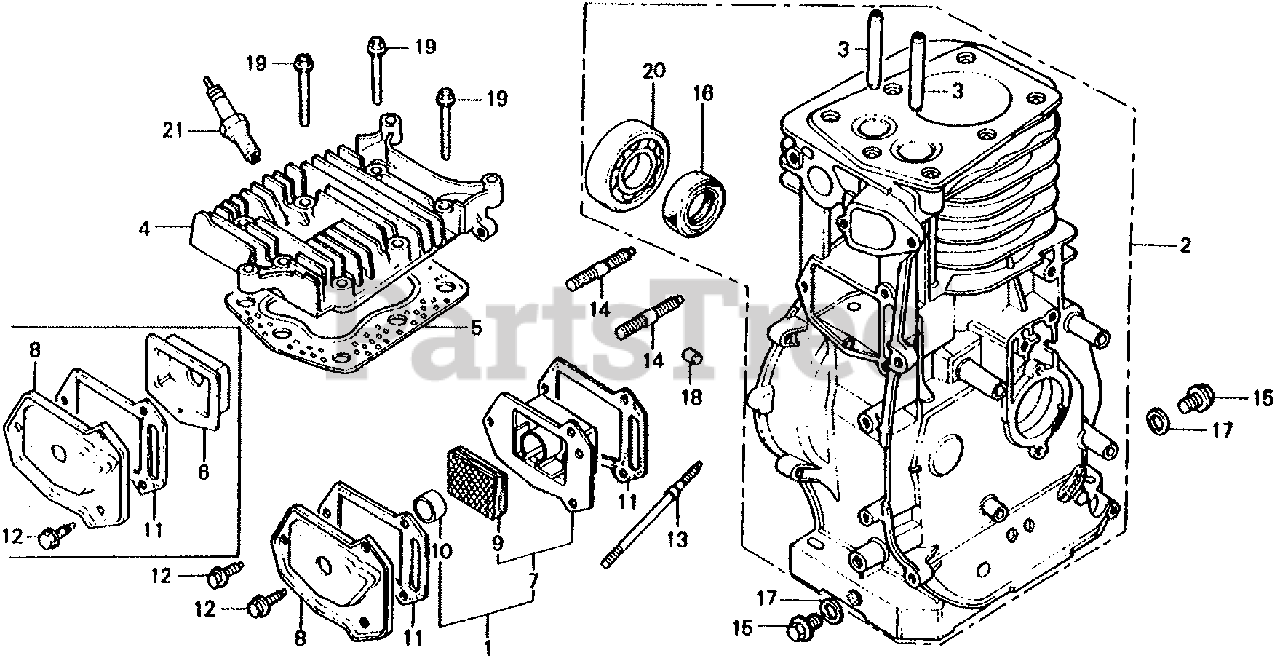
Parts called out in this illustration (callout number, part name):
1	CASE KIT, BREATHER
2	CYLINDER ASSY.
3	GUIDE, VALVE (OS)
4	CYLINDER HEAD
5	GASKET, CYLINDER HEAD
6	CASE, BREATHER
7	CASE, BREATHER
8	COVER, TAPPET ROOM
9	FILTER, BREATHER
10	SEAL, BREATHER
11	GASKET, TAPPET COVER
12	BOLT, FLANGE (6X12) (CT200)
13	BOLT, STUD (6X96)
13	BOLT, STUD (6X89)
14	BOLT, STUD (8X35)
15	BOLT, DRAIN PLUG
16	OIL SEAL (25X41X6)
17	WASHER, DRAIN PLUG (12MM)
18	PIN A, DOWEL (8X14)
19	BOLT, FLANGE (8X45)
20	BEARING, RADIAL BALL (6205)
21	SPARK PLUG (B-4H)
21	SPARK PLUG (W14F-U) (DENSO)
21	SPARK PLUG (W14FR-U) (DENSO)
21	SPARK PLUG (BP-4HS-10) (NGK)
21	SPARK PLUG (BPR-4HS-10) (NGK)
21	SPARK PLUG (BPR4HS-10) (NGK)
21	SPARK PLUG (BP4HS-10) (NGK)
21	SPARK PLUG (W14FP-UL10) (DENSO)
21	SPARK PLUG (W14FPR-UL10) (DENSO)
21	SPARK PLUG (B6HS) (NGK)
21	SPARK PLUG (BR6HS) (NGK)
21	SPARK PLUG (W20FS-U) (DENSO)
21	SPARK PLUG (W20FPR-U10) (DENSO)
